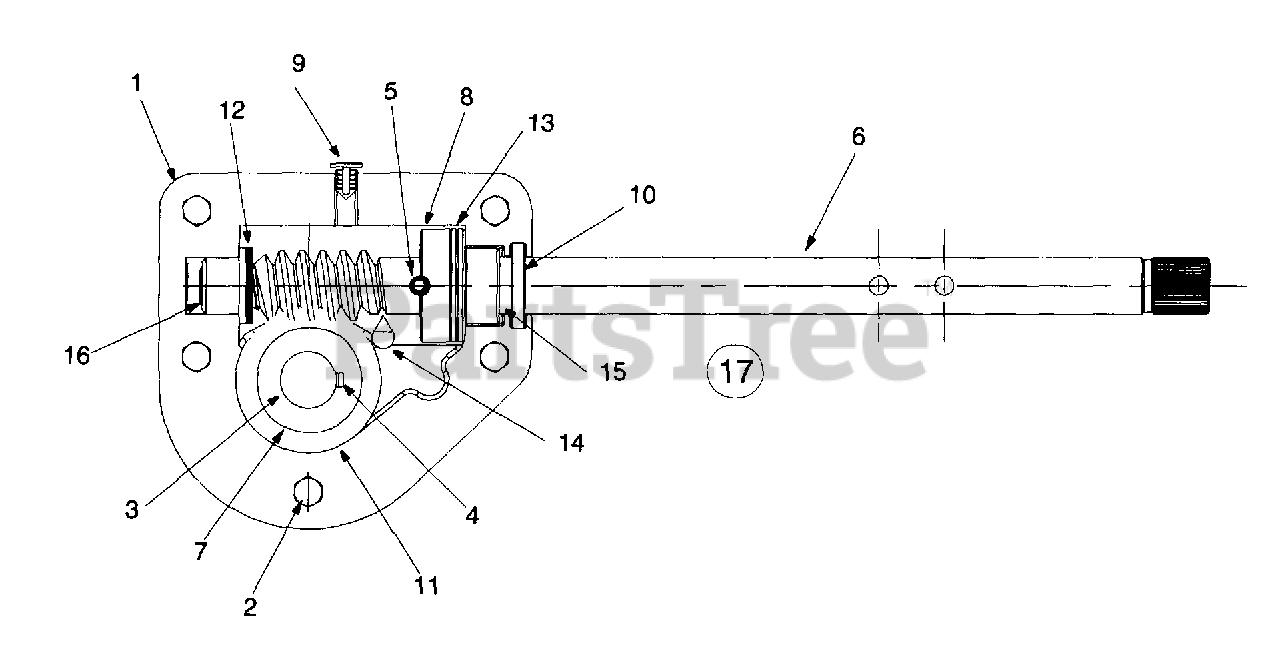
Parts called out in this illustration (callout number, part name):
1	Housing - L.H.
1	Housing - R.H.
2	Hex Screw 1/4-20 x .75
3	Spiral Axle 26" SB-950W
3	Spiral Axle 30" SB-1150W
5	Pin-Spiral
6	Shaft-Worm
7	Gear-Worm
8	Collar-Thrust
10	Seal-Oil
11	Washer-Flat
12	Washer-Flat
13	Washer-Flat
14	Grease
15	Bearing-Flange
16	Bearing-Flange
17	Ass'y. Complete 26" SB-950W
17	Ass'y. Complete 30" SB-1150W
